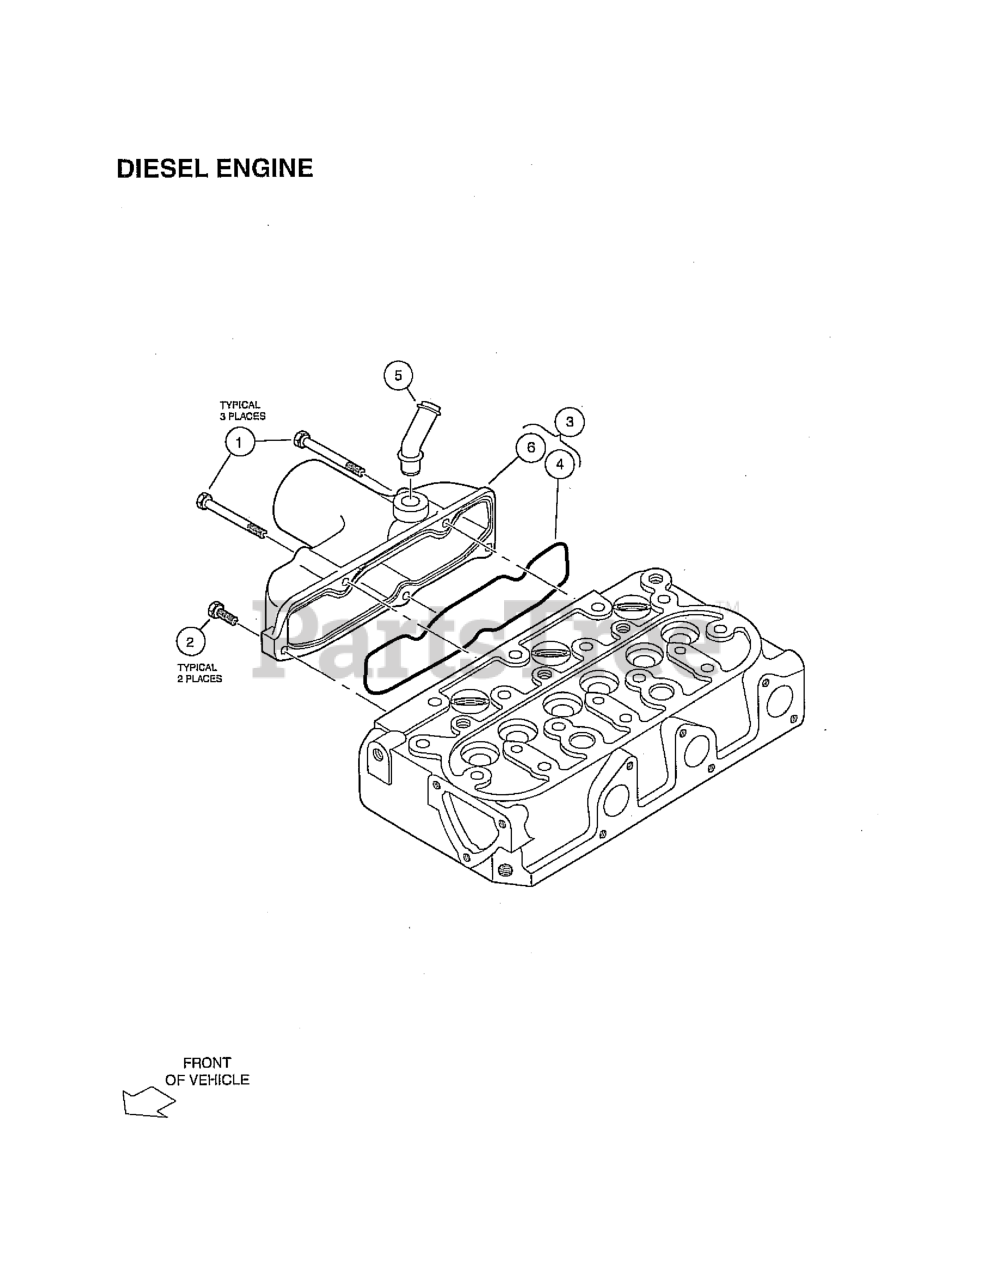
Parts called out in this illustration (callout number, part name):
1	BOLT, M6 X 1 X 45
2	BOLT, D722 INTAKE MANFLD LOWER
3	ASSY-INTAKE MANIFOLD
4	GASKET, IN-MANIFOLD
5	PIPE-BRATHR-INTAKE
